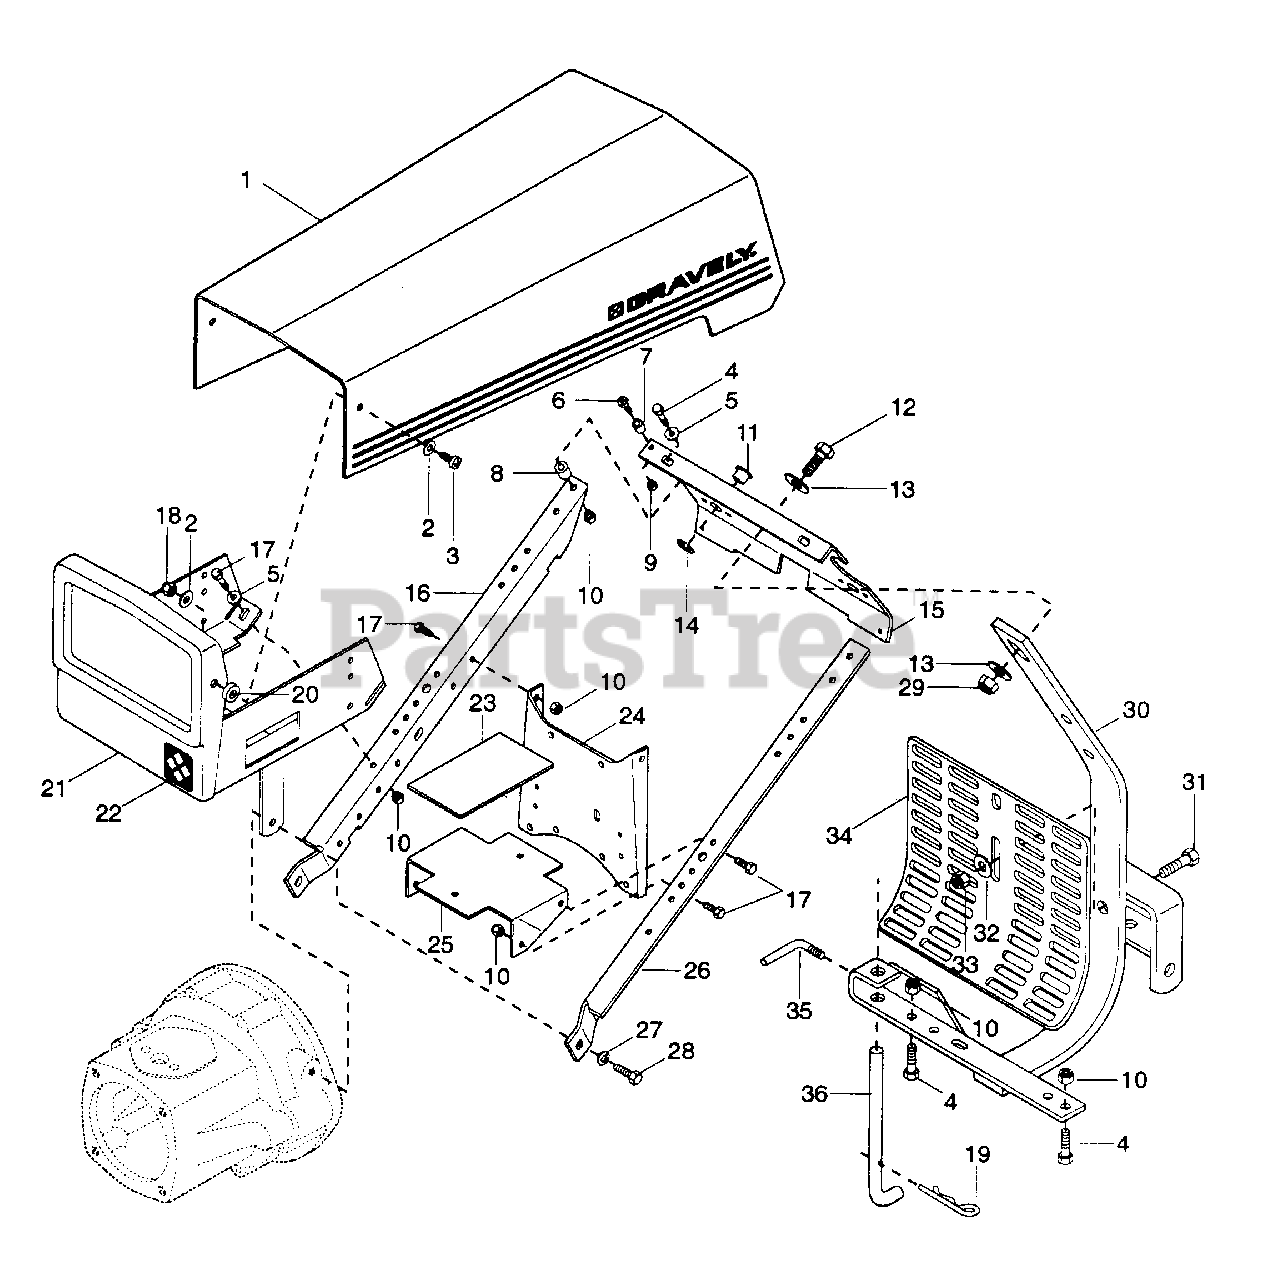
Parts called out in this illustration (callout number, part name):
1	HOOD, SILK SCREEN 10 & 12 HP
2	WSHR-FL-STL .281 X .62 X .065
3	SCR-MCH .50-20 X 1
4	BLT-HEX .38-16 X 1.50 PL GR 5
5	WSHR-FL-STL .406 X .812 X .065 PL
6	SCR-MCH 6-32 X .625
7	BUMPER
8	BUSHING
9	NUT-LK-MCH 6-32 W/INSERT
10	NUT-LK-NYL .375-16 PL
11	BUSH-FLG .515 X 1.00 X .745 NY
12	BLT-HEX .625-11 X 2.00
13	WSHR-FL-STL .656 X 1.250 X .100
14	RG-RTNG 1.000 X .748
15	PLT, SILK SCREEN MAN(MANUAL)
15	PLT, SILK SCREEN(ELECTRIC)
16	SPRT, HANDLE BAR R.H.
17	BLT-HEX .380-16 X .875
18	NUT-LK-NYL .250-20 PL
19	PIN-HAIR-INT .15 X 2.937
20	BUSH., F .280 X .750 X .318 NY
21	WLDMT, BATTERY BRACKET
22	DECAL, COMM. FRONT
23	PAD, GAS TANK
24	BRKT
25	BRKT, TANK SUPPORT
26	SPRT, HANDLE BAR L.H.
27	WSHR-LOCK .50 REG
28	BLT-HEX .50-13 X 1 PL GR 5
29	NUT-LK-NYL .625-11 PL
30	WLDMT, HITCH 10 & 12 HP
31	BLT-HEX .50-13 X 1.50 PL GR 5
32	WSHR-FL-STL .531 X 1.250 X .100
33	NUT-LK-NYL .50-13 PL
34	GRD, ENGINE
35	HNDL, ADJUSTING
36	STAND, KICK
